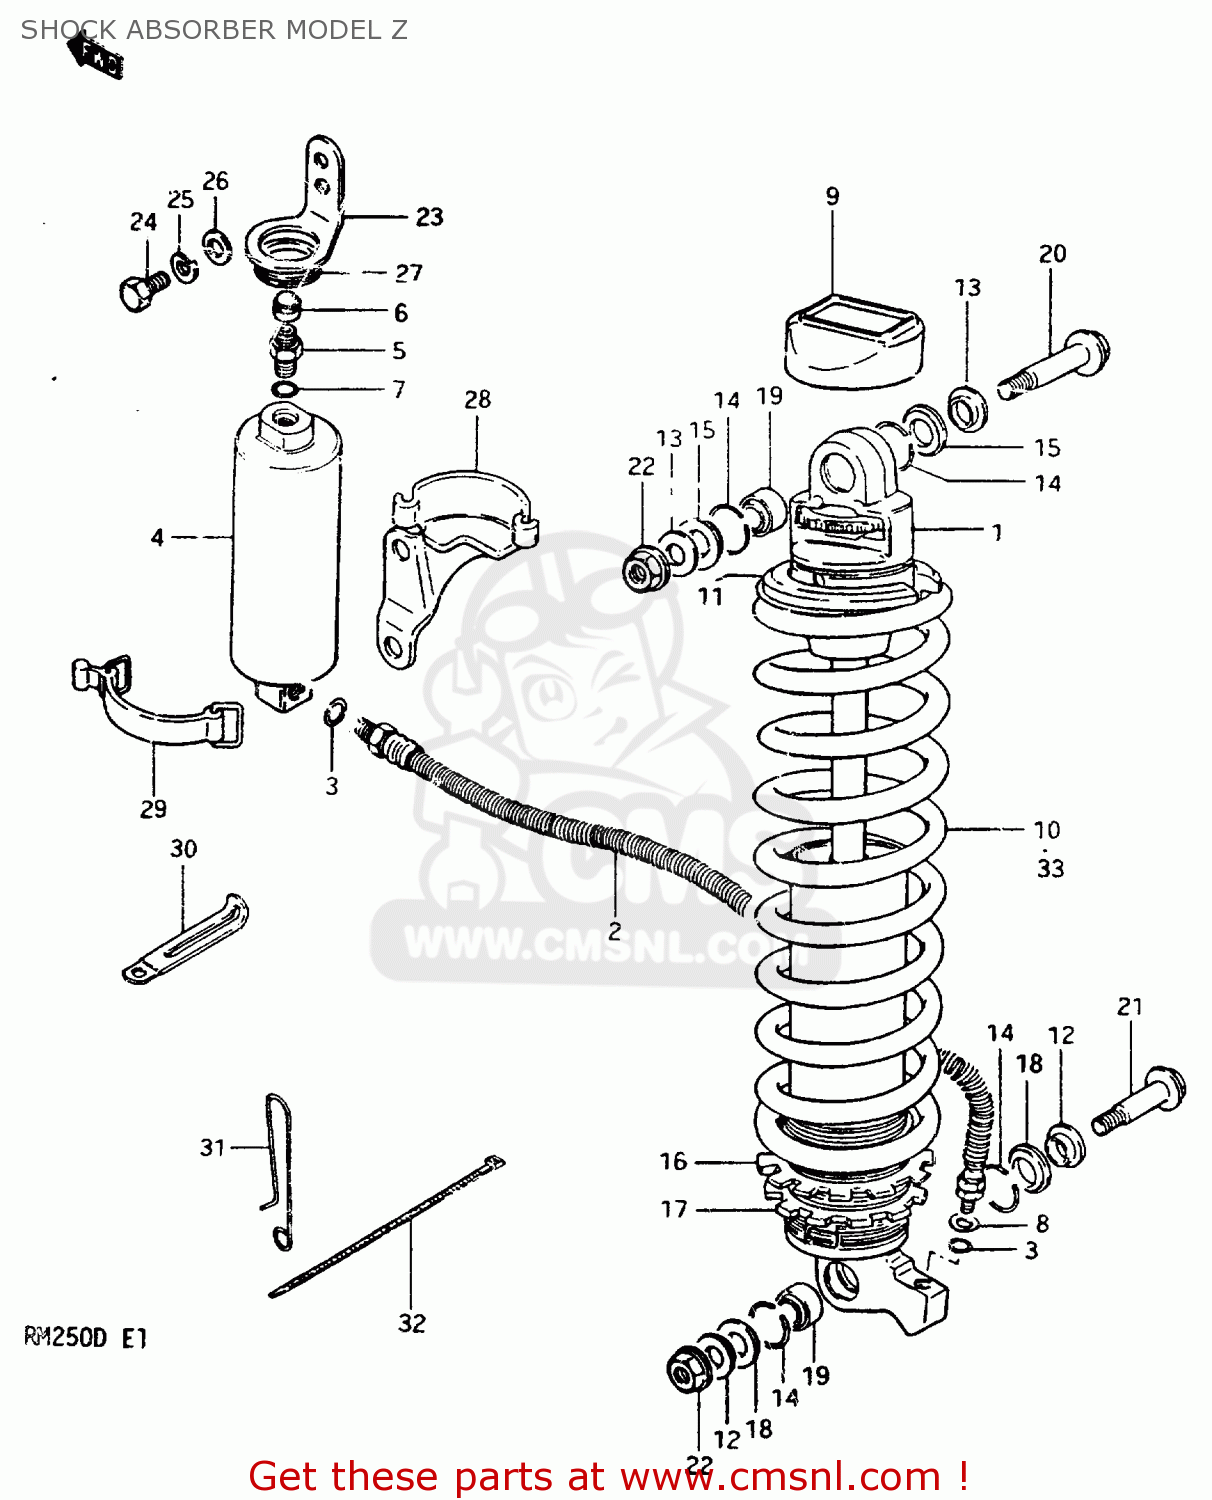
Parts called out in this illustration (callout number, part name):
1	ABSORBER ASSEMBLY,REAR SHOCK
2	HOSE,REAR SHOCK ABSORBER
3	O-RING,RESERVE TANK
4	RESERVE TANK,REAR SHOCK
5	VALVE ASSEMBLY,REAR CUSHION
6	CAP,VALVE AIR
7	O RING
8	WASHER,REAR SHOCK HOSE
9	CAP REAR SHOCK
10	SPRING
11	SPRING, GUIDE
12	COLLAR
13	SPACER,REAR SHOCK,UPPER
14	RING,STOPPER
15	DUST SEAL,UPR
16	GUIDE,SPRING
17	GUIDE,REAR SHOCK ABSORBER SPRING
18	DUST SEAL,LWR
19	BEARING
20	BOLT
21	BOLT(10X54)
22	NUT
23	BRACKET,RESERVOIR TANK
24	BOLT
25	WASHER,LOCK
26	WASHER
27	CUSHION,RESERVOIR TANK
28	BRACKET,RESERVOIR TANK
29	BAND
30	CLAMP
31	GUIDE RES HOSE CLAMP
32	CLAMP
33	SPRING
